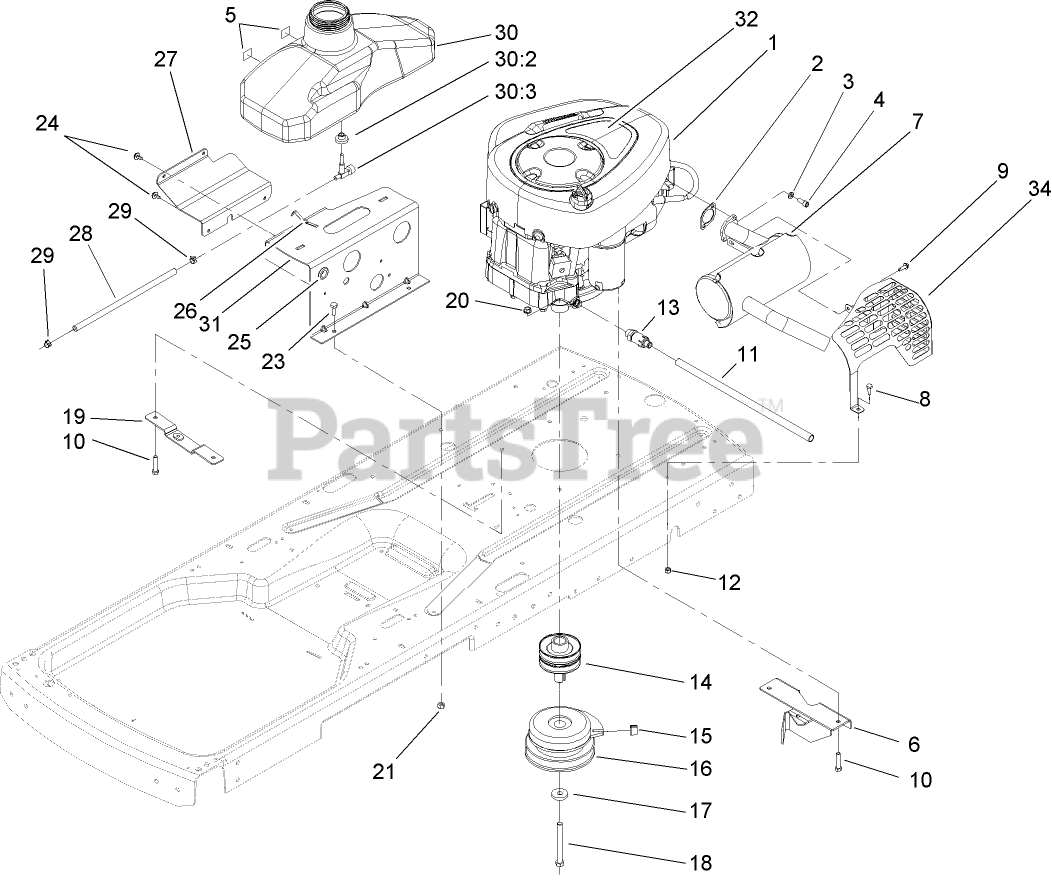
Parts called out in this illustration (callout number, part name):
1	Loose Parts Package
2	GASKET-EXHAUST
3	WASHER-LOCK
4	SCREW-HSH
5	FOAM-SWITCH, SEAT
6	BRACKET-PIVOT
7	MUFFLER
8	SCREW-HH
9	SCREW-HWH, THREAD ROLL
10	SCREW-HH
11	TUBE-DRAIN, OIL
12	NUT-LOCK, NI
13	VALVE-DRAIN, OIL
14	PULLEY-ENGINE
15	BUMPER
16	CLUTCH-ELECTRIC
17	WASHER
18	SCREW-HH
19	PLATE-MOUNT, IDLER
20	NUT-HF
21	NUT-LOCK, NI
23	SCREW-HH
24	SCREW-HHFTF
25	GROMMET
26	SPRING
27	PLATE-SUPPORT
28	HOSE-FUEL
29	CLAMP-HOSE
30	GAS TANK ASM
30:2	BUSHING
30:3	VALVE-FUEL
31	PLATE-TANK
32	DECAL-ENGINE, I/C
34	GUARD-MUFFLER
